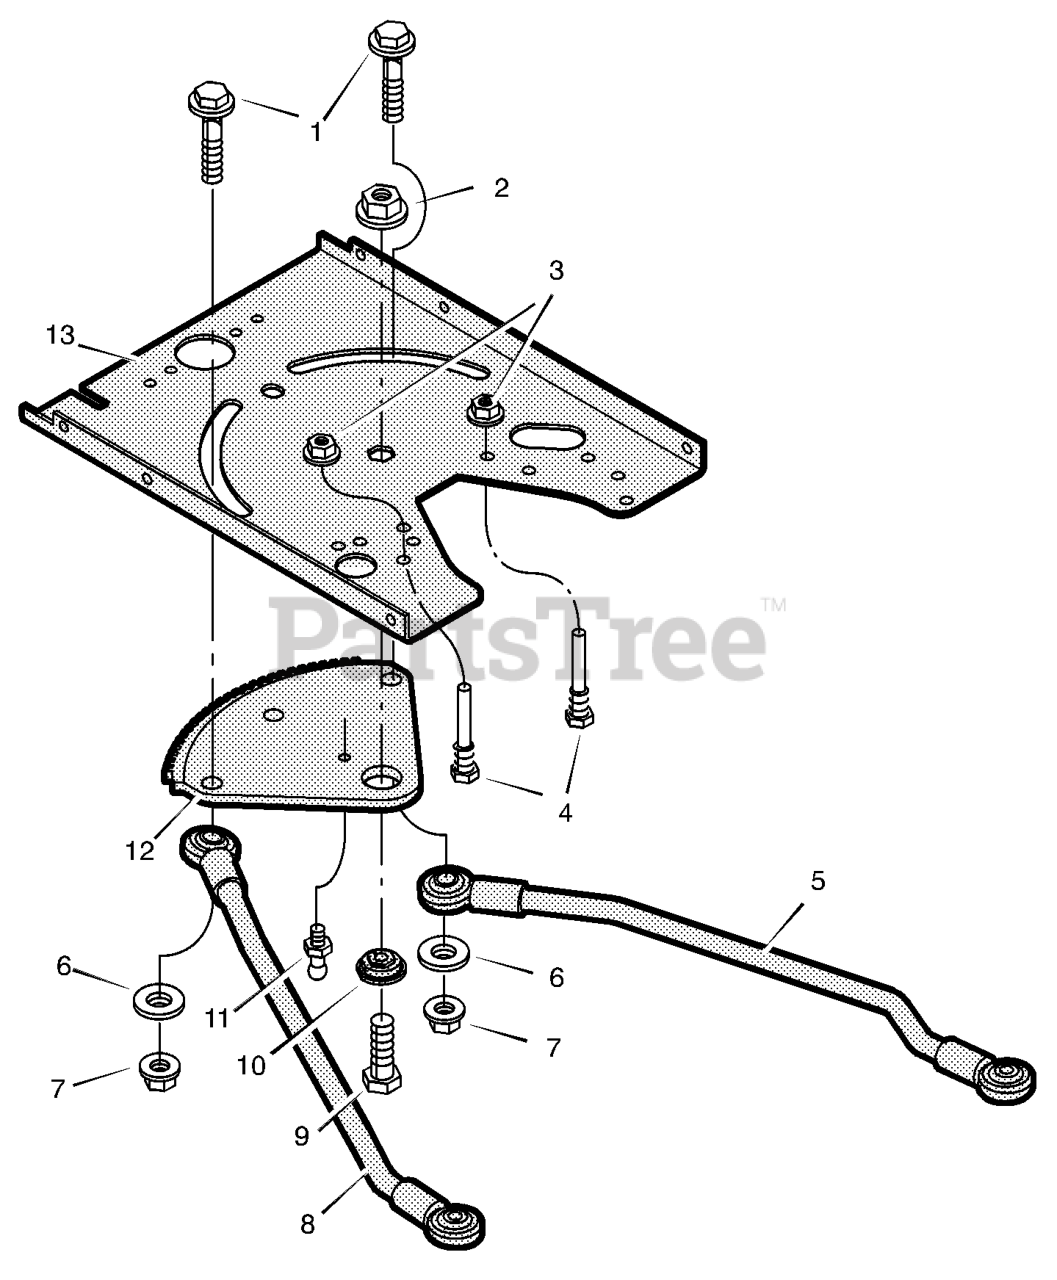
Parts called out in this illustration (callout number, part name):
1	Bolt, Shoulder
2	Nut, Lock
3	Nut, Flange
4	Guide, Screw
5	Link, Left Drag
7	Nut, Flange
8	Link, Right Drag
9	CAPSCREW, Hex Head, 5/16-18 x 1
10	Bearing, Sector Gear
11	Fitting, Lub
12	Gear, Sector
13	Plate, Steering
